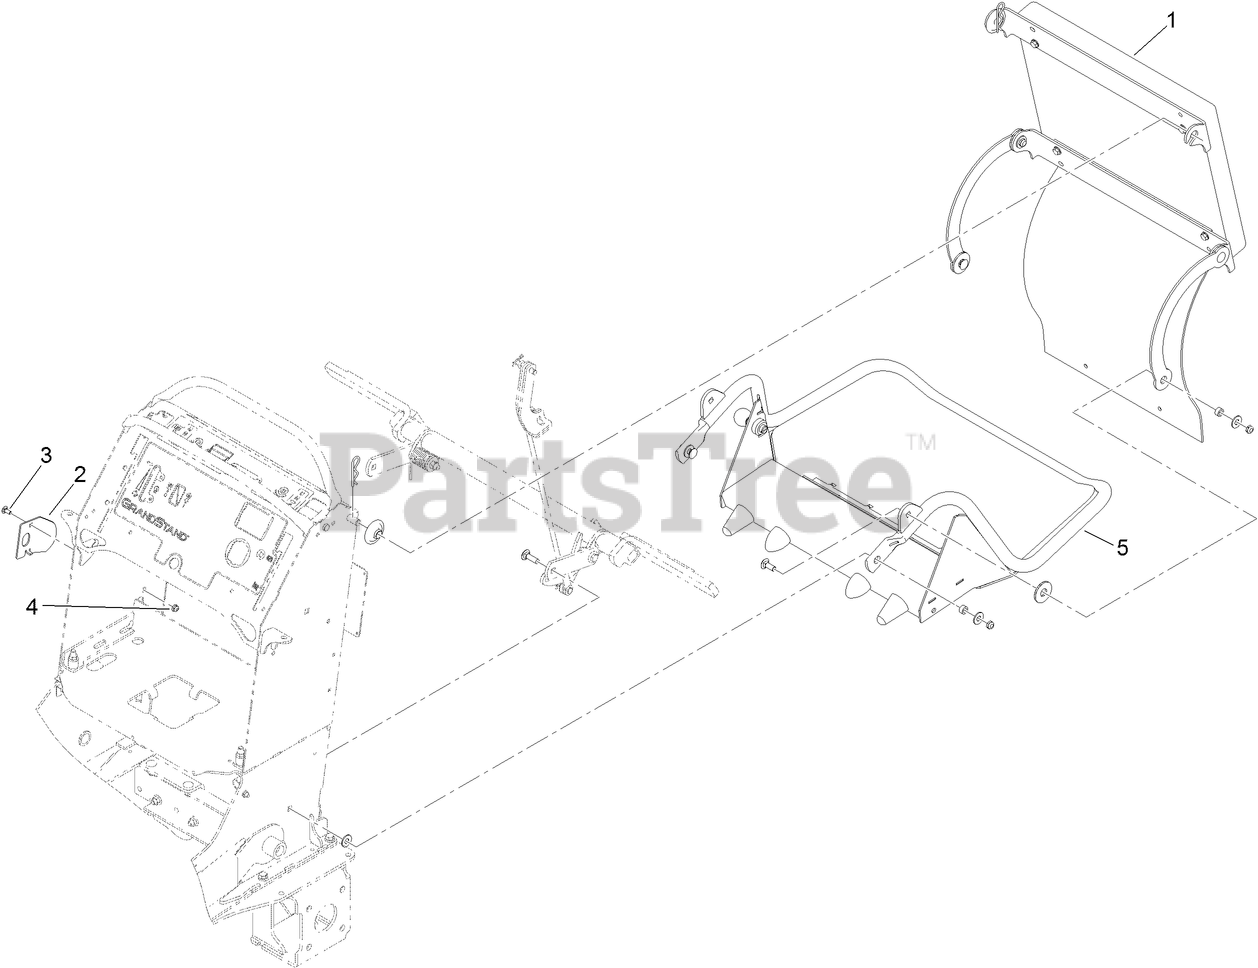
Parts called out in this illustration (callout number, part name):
1	CUSHION ASM
2	PLATE-STRIKER
3	SCREW-CARR
4	NUT-HF
5	PLATFORM ASM
